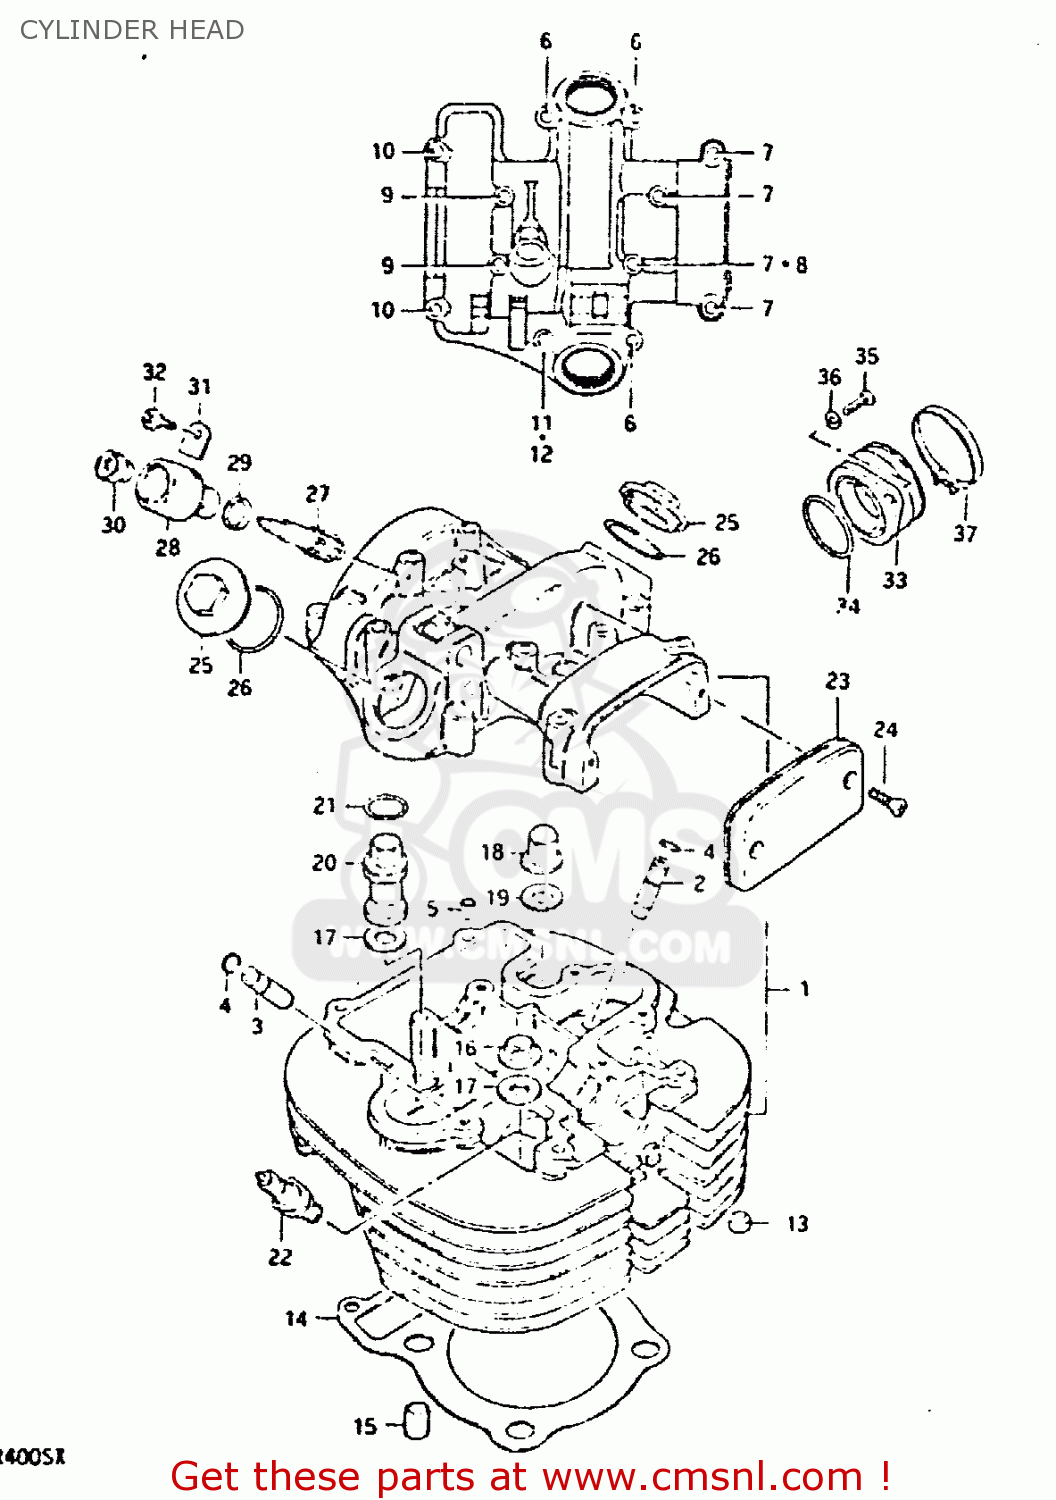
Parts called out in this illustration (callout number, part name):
1	HEAD SET,CYLINDER
2	GUIDE,INTAKE VALVE
3	GUIDE,EXHAUST VALVE
4	RING,SNAP
5	PIN(6.2X8X11)
6	BOLT 6X35
7	BOLT ,6X50
8	BOLT
9	BOLT 6X65
10	BOLT
11	BOLT (6X60)
12	WASHER
13	PAD,CYLINDER
14	GASKET,CYLINDER HEAD (NAS)
15	PIN
16	NUT
17	WASHER(10.5X22X2.3)
18	NUT
19	GASKET (NAS)
20	NUT,CYLINDER HEAD SEAL
21	O RING(D:2.4,ID:17.8)
22	SPARK PLUG DR8ES-L
23	CAP,CYLINDER HEAD COVER
24	SCREW
25	CAP,INSPECTION
26	O RING(D:3,ID:29.5)
27	GEAR,TACHOMETER DRIVEN
28	SLEEVE,TACHOMETER DRIVE
29	SEAL,TACHOMETER DRIVEN
30	SEAL,OIL(5X12X8)
31	PLATE,TACH DRIVE GEAR SLEEVE
32	SCREW(5X12)
33	PIPE,INTAKE
34	O-RING (D:2.4 ID:39.7)
35	SCREW
36	LOCK WASHER
37	CLAMP
